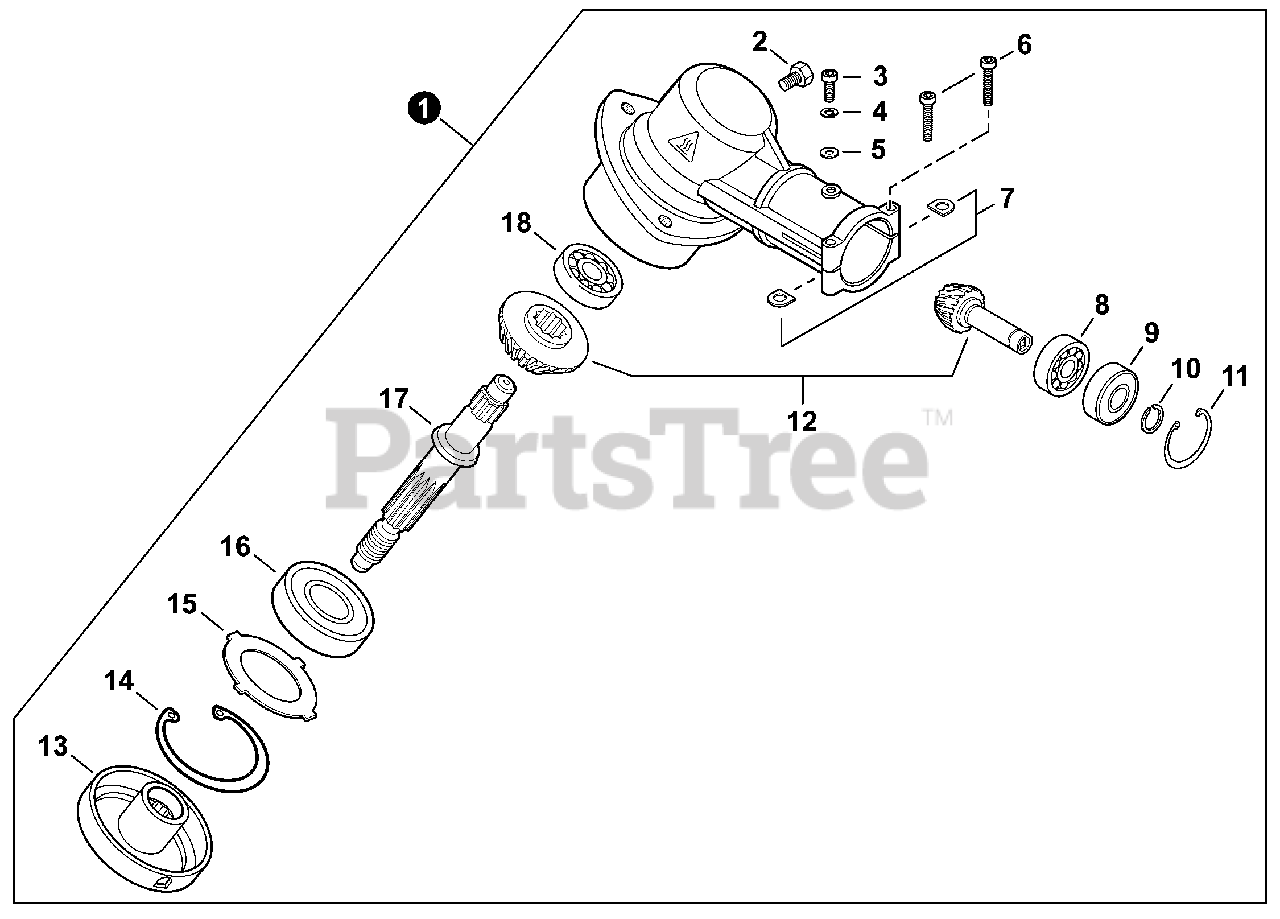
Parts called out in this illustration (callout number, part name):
1	GEAR CASE ASSY
2	BOLT M8x8
3	BOLT, TORX 5x10
4	WASHER, SPRING 5
5	WASHER, FLAT 5.5x10x0.8
6	BOLT, TORX 5x25
7	D-WASHER
8	BEARING, BALL 6900
9	BEARING, BALL 6900Z
10	RING, SNAP 10
11	RING, SNAP 22
12	GEAR SET
13	PLATE, ADAPTOR - UPPER
14	RING, SNAP 32
16	BEARING, BALL 6201
17	SHAFT, GEAR
18	BEARING, BALL 609
